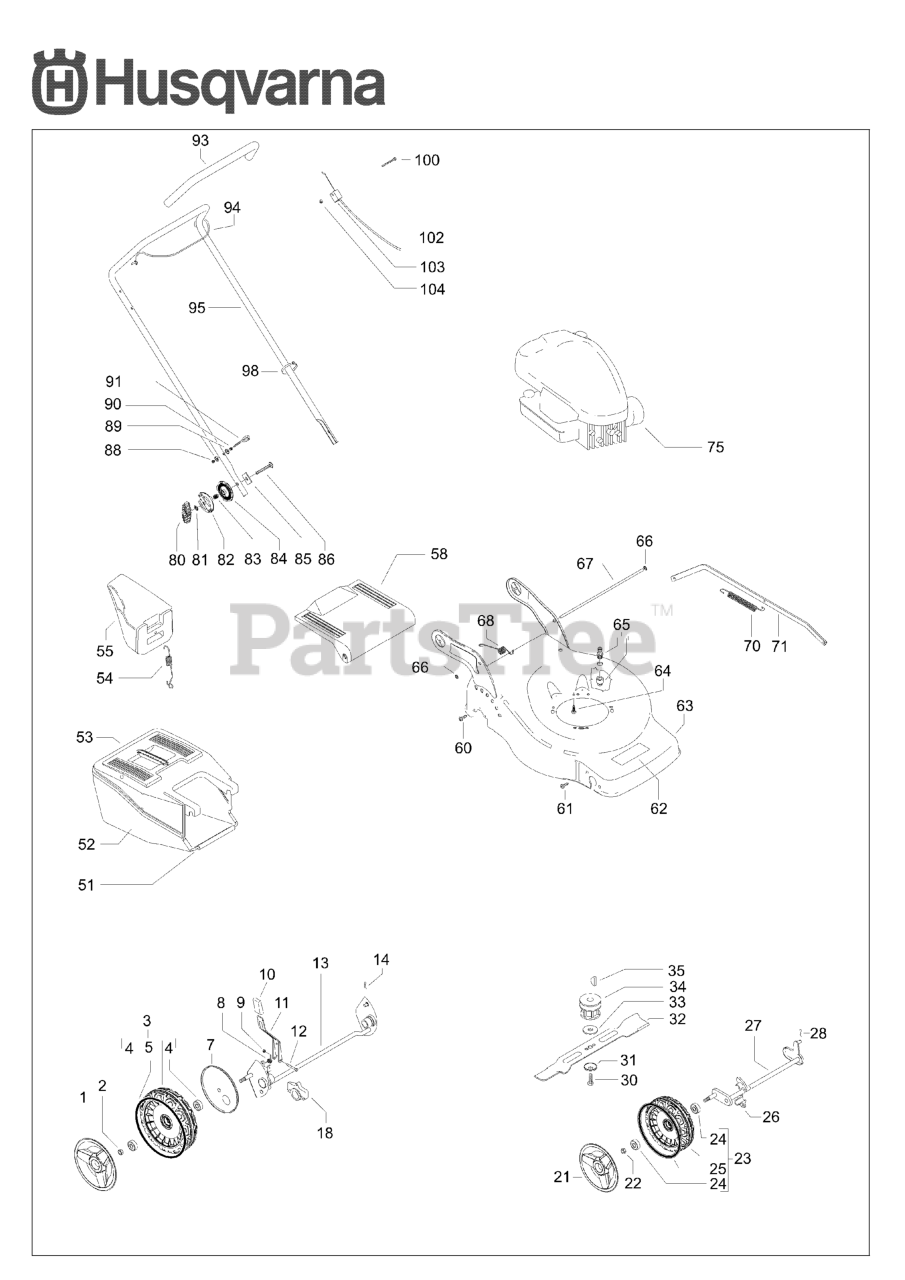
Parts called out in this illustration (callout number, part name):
11	LIFTING LEVER ASSY FOR REAR AX
32	MOWER BLADE COMBI
102	BRAKE WIRE
